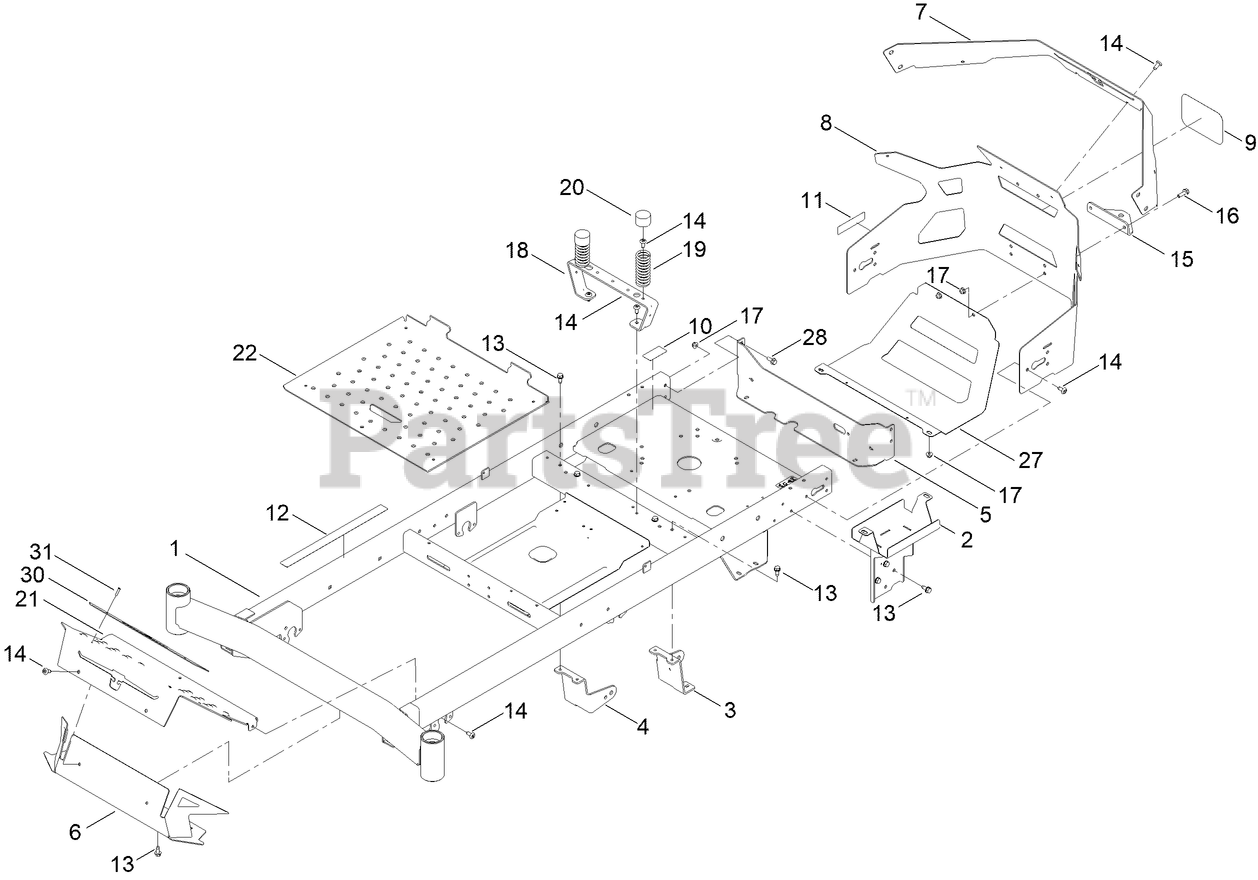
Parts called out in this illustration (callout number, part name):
1	SERVICE ASM-FRAME, TC
2	WA-BATTERY MOUNT
3	MOUNT-DRIVE, LH
4	MOUNT-DRIVE, RH
5	PLATE-MOUNT
6	FOOTREST-TOP
7	PLATE-REAR CLADDING TC
8	GUARD-ENGINE TC
9	DECAL
10	DECAL-BYPASS
11	DECAL-SPARK ARRESTER
12	DECAL-WARNING
13	SCREW-HWHTF
15	BRACKET-HITCH
16	SCREW-HHF
17	NUT-HF
18	SUPPORT-SEAT
19	SPRING-COMPRESSION
20	CAP-PROTECTOR
21	PLATE-KICK
22	PAN-FLOOR
27	GUARD-MUFFLER [BLACK]
28	SCREW-HHF
30	PLATE- TOEBOARD
31	RIVET-TRIFOLD
